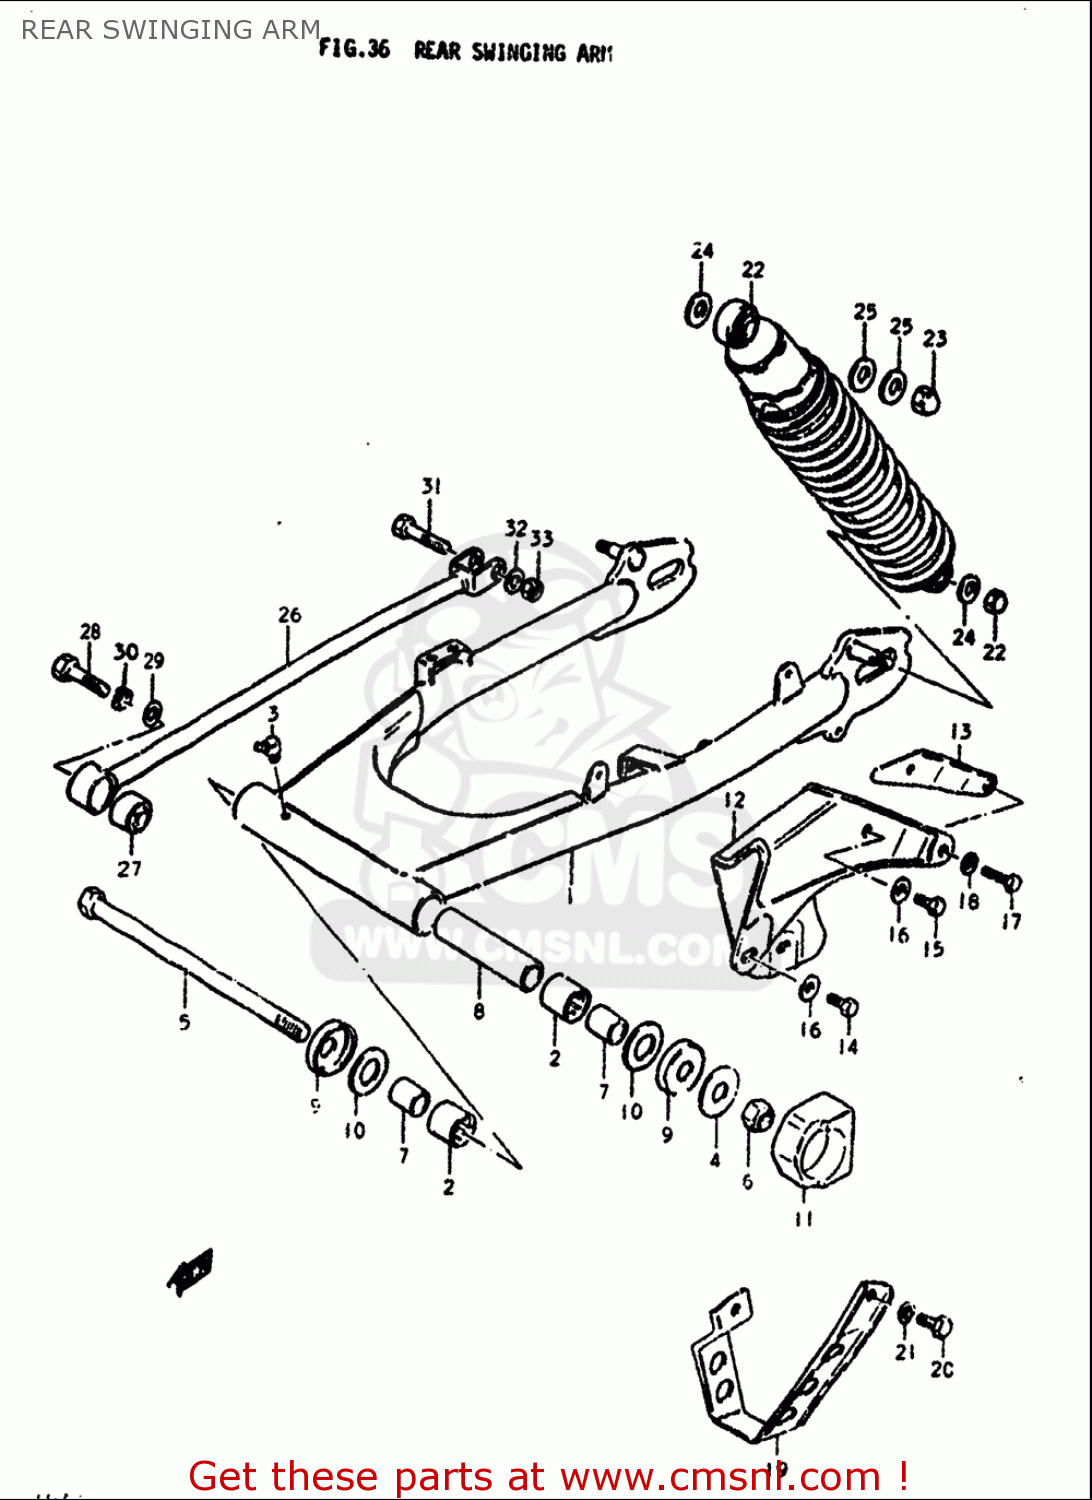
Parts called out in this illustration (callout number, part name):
2	BEARING(22X29X20)
3	NIPPLE,GREASE
5	SHAFT,REAR SWING ARM
6	NUT 14MM
7	SPACER,RR SWGARM PIVOT
8	SPACER (16.2X21.7X142)
9	COVER,RR SWGARM DUST SEAL
10	WASHER
11	BUFFER,CHAIN TOUCH DEFENSE
13	REINFORCEMENT,CHAIN CASE
14	BOLT
15	BOLT(6X8)
16	WASHER
17	BOLT
18	WASHER
20	BOLT
21	WASHER,LOCK
23	NUT
24	WASHER
25	WASHER (10.5X24X2.3)
27	BUSH
28	BOLT
29	WASHER
30	WASHER,LOCK
31	BOLT
32	WASHER
33	NUT
